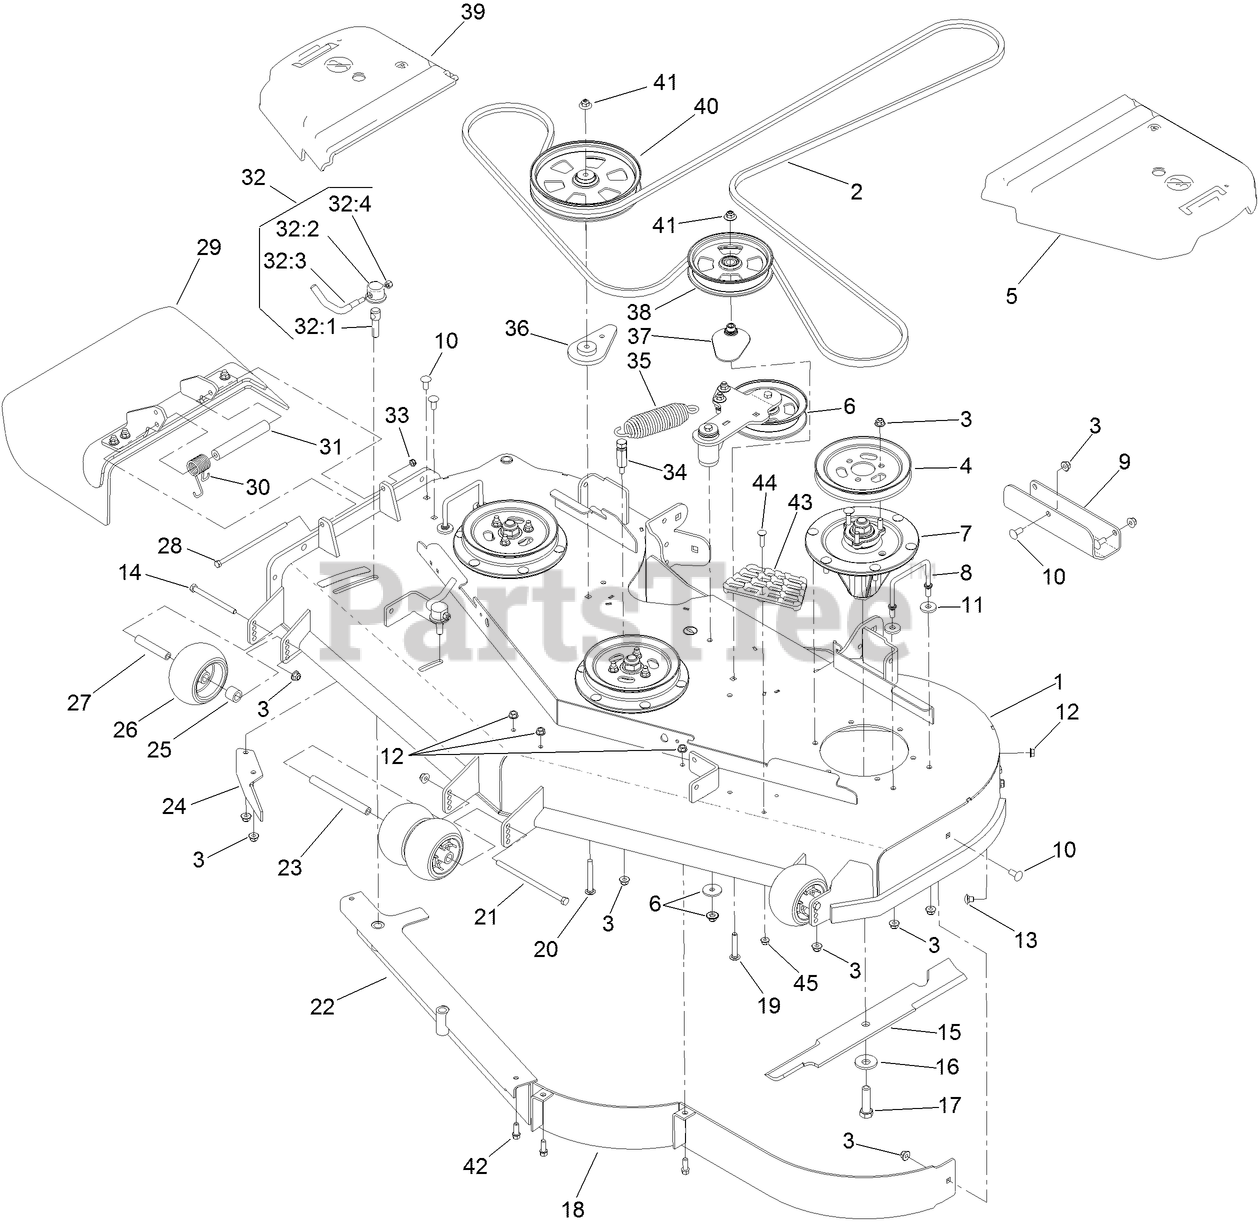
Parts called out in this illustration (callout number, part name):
1	DECK DECAL ASM
2	BELT-V
3	NUT-HF, NI
4	PULLEY
5	COVER-BELT, LH
6	IDLER ARM ASM
7	SPINDLE ASM
8	WIREFORM-COVER
9	PLATE-SKID
10	SCREW-CARR
11	WASHER
12	NUT-HHF, WHIZ
13	SCREW-CARR
14	SCREW-HH
15	BLADE-HI FLOW
16	WASHER-BLADE BOLT, HEAVY
17	SCREW-BLADE
19	BOLT-CARR, SHORT NECK
20	SCREW-CARR
21	SCREW-HH
22	BAFFLE ASM
23	SPACER-WHEEL
24	BAFFLE-DISCHARGE
25	TUBE-SPACER
26	ROLLER-SCALP, ANTI
27	TUBE-SPANNER
28	SCREW-HH
29	RUBBER DEFLECTOR ASM
30	SPRING-TORSION
31	SPACER
32	LEVER ASM
32:1	SCREW-LOCK
32:2	CAP-LOCK
32:4	NUT-LOCK, NI
33	NUT-LOCK, NI
34	ANCHOR-SPRING, TALL
35	SPRING-EXTENSION
36	SPACER-IDLER
37	SPACER-PULLEY
38	PULLEY-IDLER, FLAT
39	COVER-BELT, RH
40	PULLEY-IDLER,FLAT
41	NUT-FLANGE, NI
43	STEP-DECK
44	SCREW-CARR
45	NUT-HF, NI
